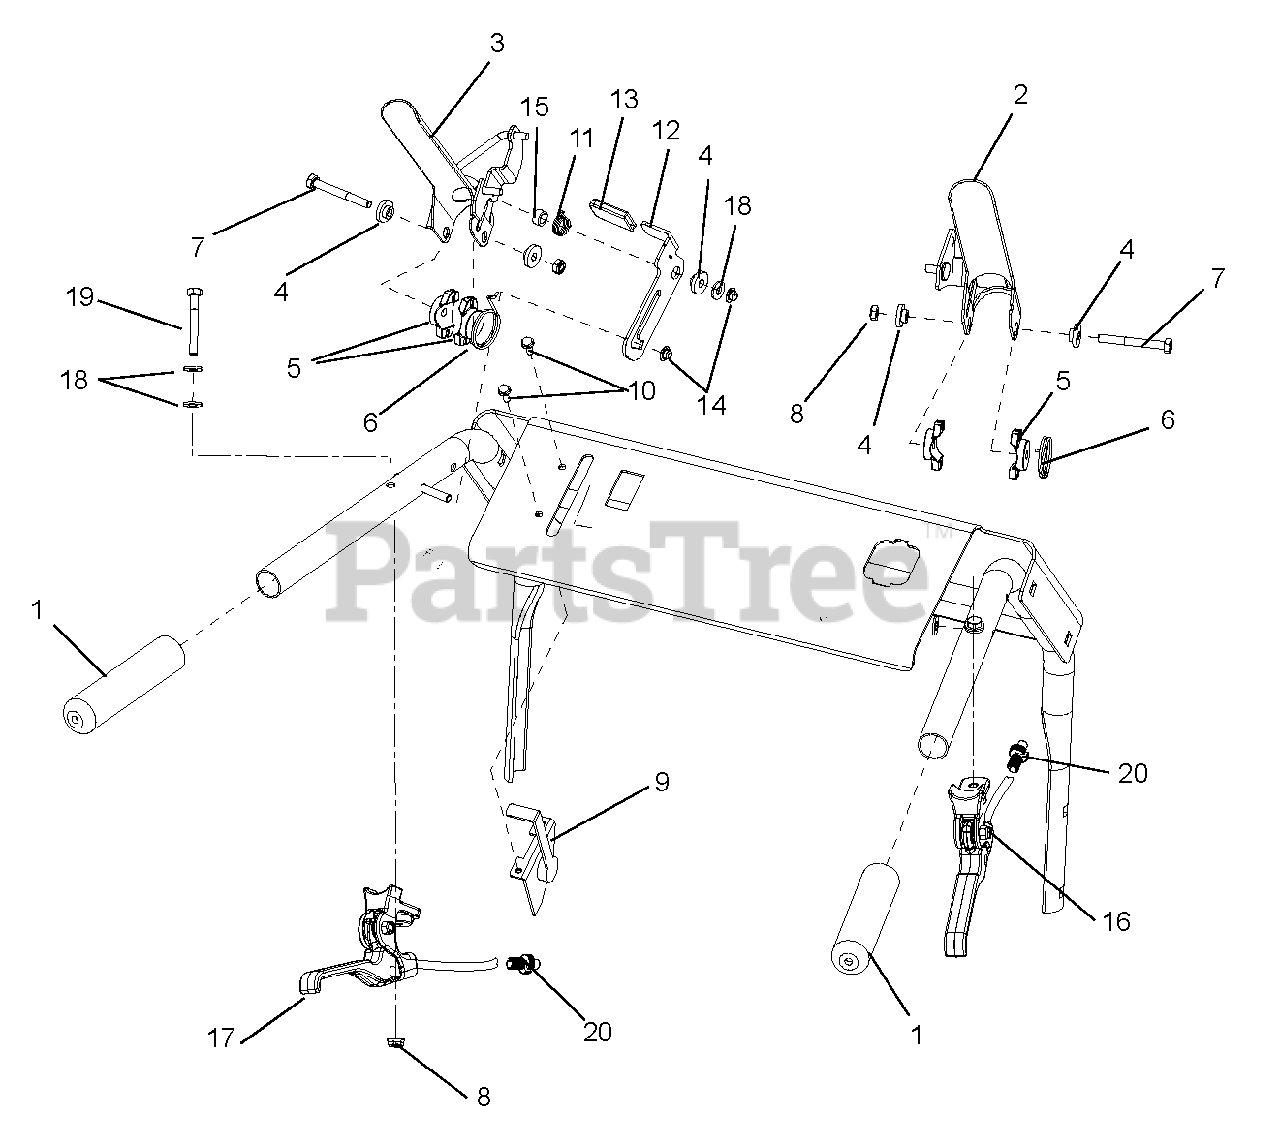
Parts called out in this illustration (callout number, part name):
1	Grip, Handle
2	Paddle, Pillow Brake
3	Weldment, Paddle Left Hand CE
4	Bushing, Flange .266 x .42 x .150 x .750
5	Spacer, Handlebar
6	Spring, Torsion
7	Bolt, Hex .25-20 x 2.25
8	Nut, Nylon Jam .250-20
9	Cable, Throttle
10	Screw, Tapping 10-24 x .50 Hex Washer Head
11	Spring, Torsion
12	Bracket - Lever, Interlock
13	Grip, Thumb Latch
14	Nut, Push .25
15	Tube, Spacer .33 x .50
16	Lever, Control With Cable Forward
17	Lever, Control With Cable Reverse
18	Washer, Flat Steel .281 x .62 x 0.65
19	Bolt, Hex .25-20 x 2.00
20	Cable Adjuster, Steel (Service Only)
